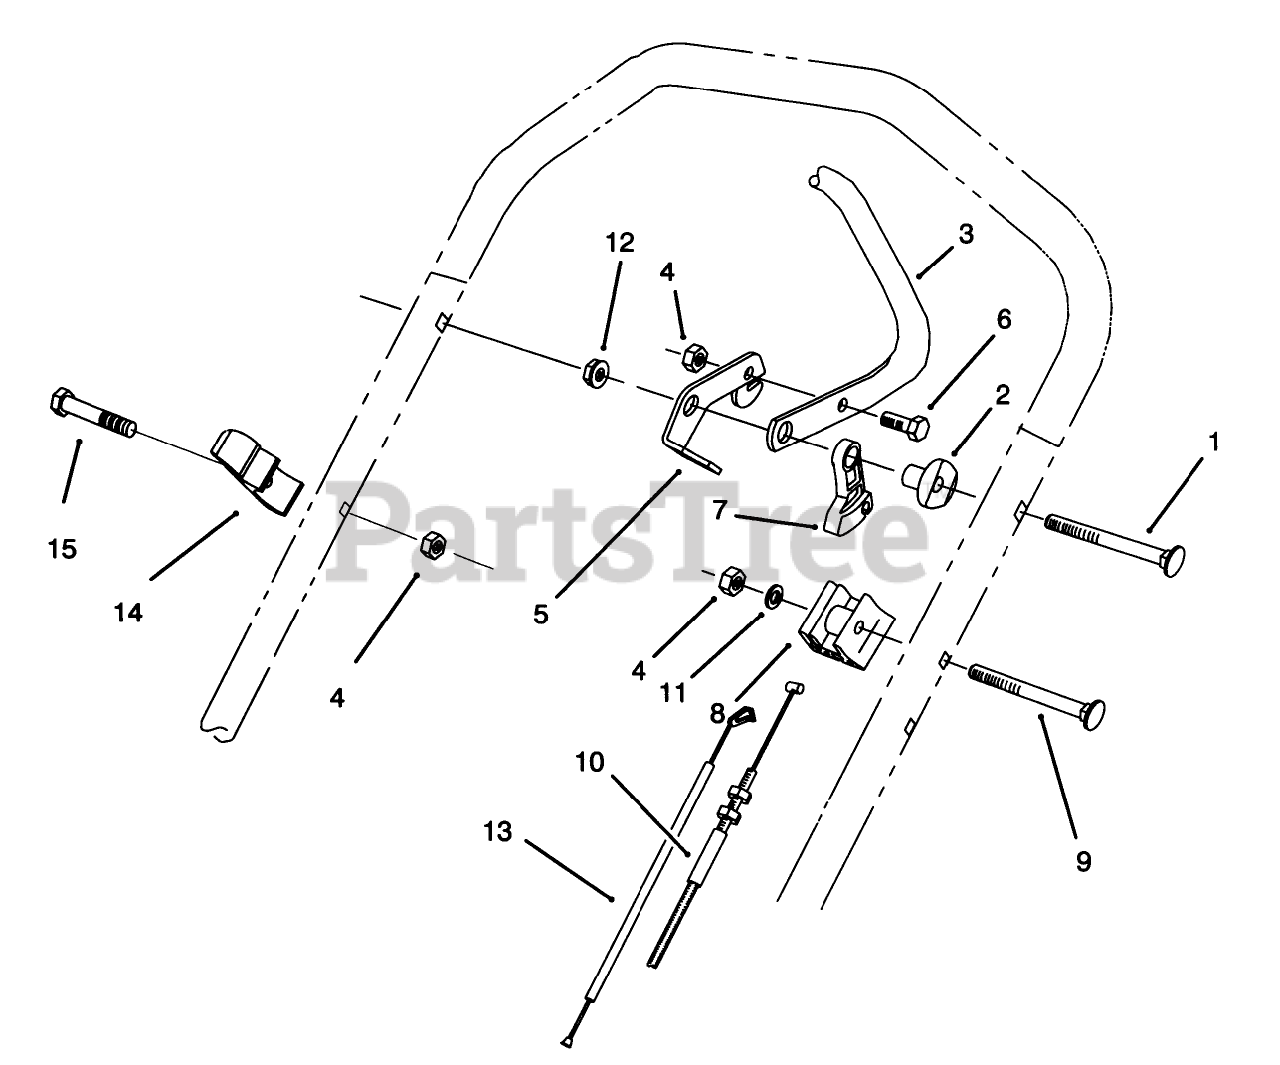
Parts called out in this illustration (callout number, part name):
1	SCREW-HANDLE
2	SPACER-SUPPORT
4	NUT-LOCK, NI
5	LEVER-CONTROL
6	SCREW-HH
7	LEVER-TRACTION
8	SUPPORT-CABLE
9	SCREW-HANDLE
10	CABLE-TRACTION
11	WASHER-FLAT
12	NUT-LOCK, NI
13	CABLE - BRAKE
14	GUIDE - ROPE
